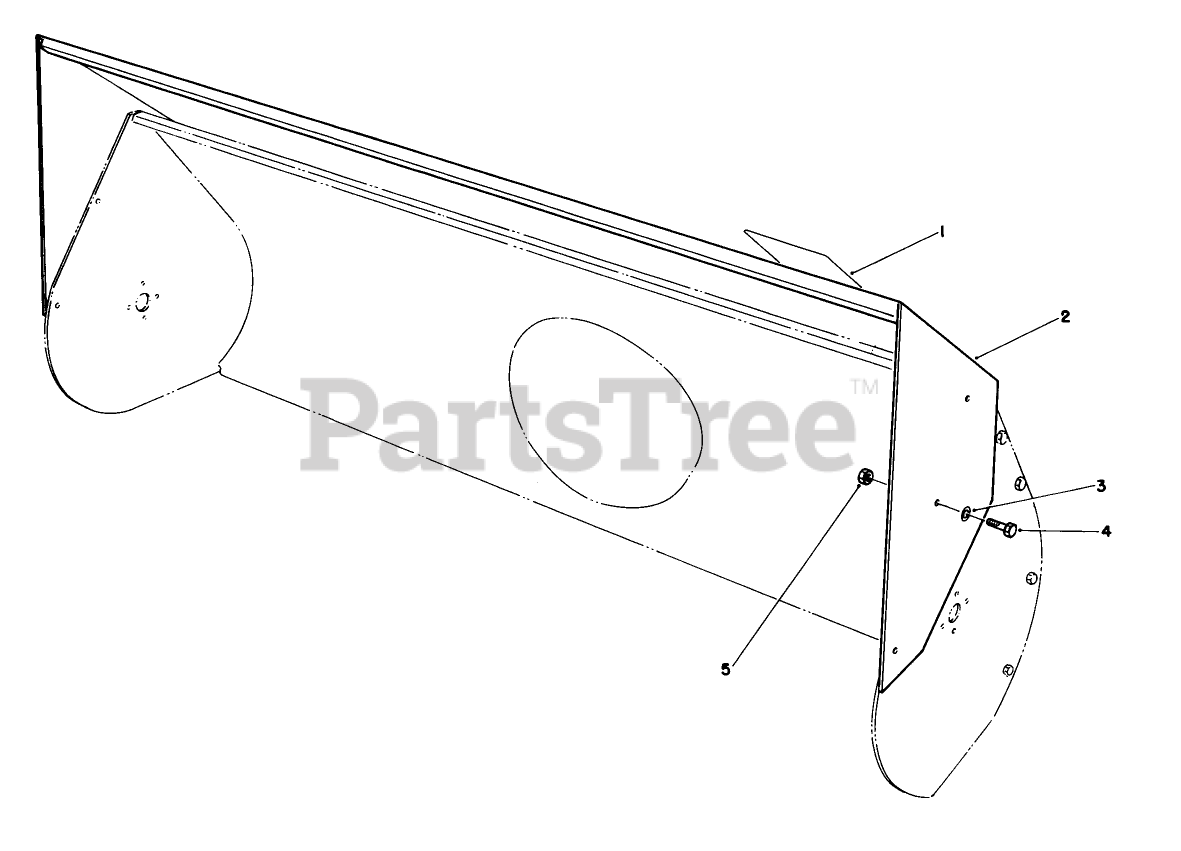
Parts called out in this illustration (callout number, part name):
2	Extension-Auger,44"
3	WASHER-FLAT
4	SCREW-HH
5	NUT-LOCK, NI
